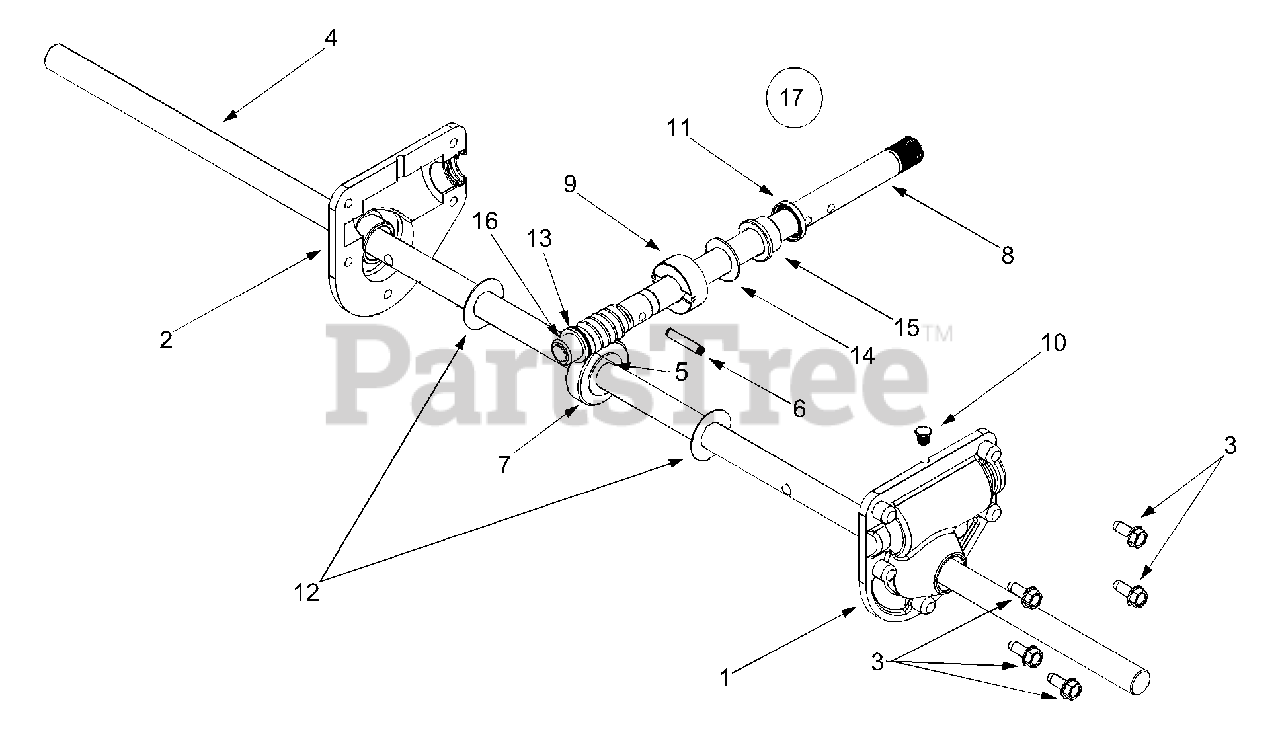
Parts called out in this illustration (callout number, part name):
1	RH Reducer Housing
2	LH Reducer Housing
3	Hex Screw 1/4-20 x .75
4	Spiral Axle 28"
5	Key
6	Pin-Spiral
7	Worm Gear, 20T
8	Worm Shaft
9	Thrust Collar
10	Grease Plug
11	Grease Seal
12	Flat Washer .76 x 1.5 x .030
13	Flat Washer .508 x 1.0 x .020
14	Flat Washer .76 x 1.5 x .060
15	Flange Bearing .75 x 1.0 x .59
16	Flange Bearing .75 x 1.0 x .925
17	Ass'y. Complete 28"
